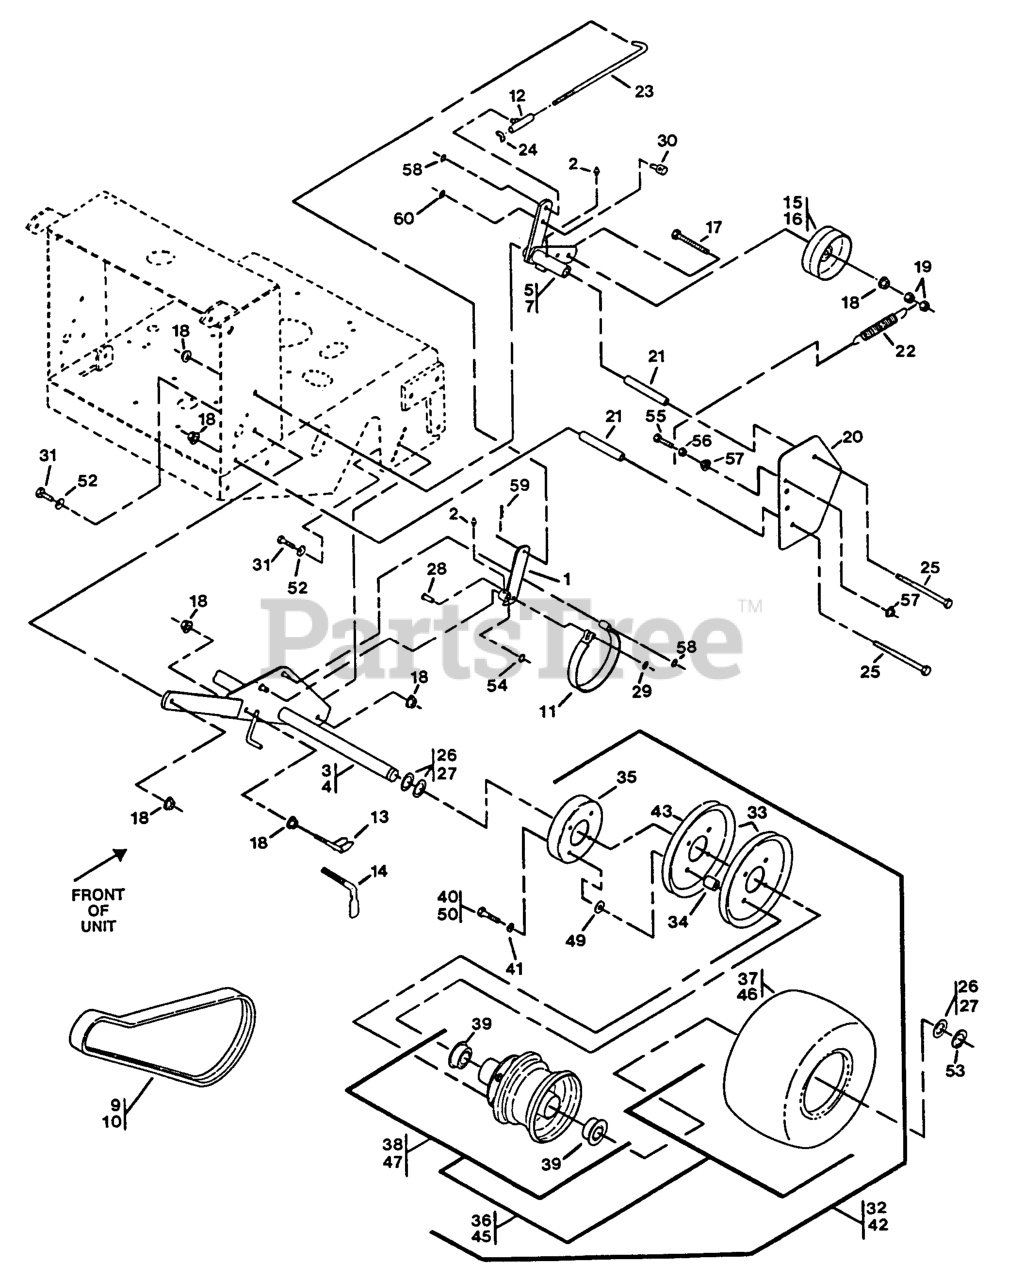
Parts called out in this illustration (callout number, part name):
9	BELT,WHEEL DRIVE
10	BELT-WHEEL, DRIVE
11	BAND-BRAKE
14	SCRAPER
15	IDLER-WHEEL, DRIVE
16	IDLER-WHEEL, DRIVE
20	SHIELD-WHEEL, DRIVE
21	SPACER-SHIELD
22	SPRING-EXTENSION
23	ROD-BRAKE
24	WINGNUT-NYLOCK
26	WASHER-SPACER
28	PIN-CLEVIS
29	RING-RETAIN,PUSH,EXT,FLAT
30	SWIVEL-SHORT, ADJUSTABLE
33	SHEAVE-WHEEL, DRIVE
34	WHEEL AND HUB ASM
35	DRUM-BRAKE
38	WHEEL AND HUB ASM
39	BEARING-FLANGED
41	WASHER-LOCK
42	DRIVE WHEEL ASM
43	SHEAVE-WHEEL, DRIVE
45	WHEEL AND TIRE ASM
47	WHEEL AND HUB ASM
53	RING-SNAP
59	PIN-COTTER
